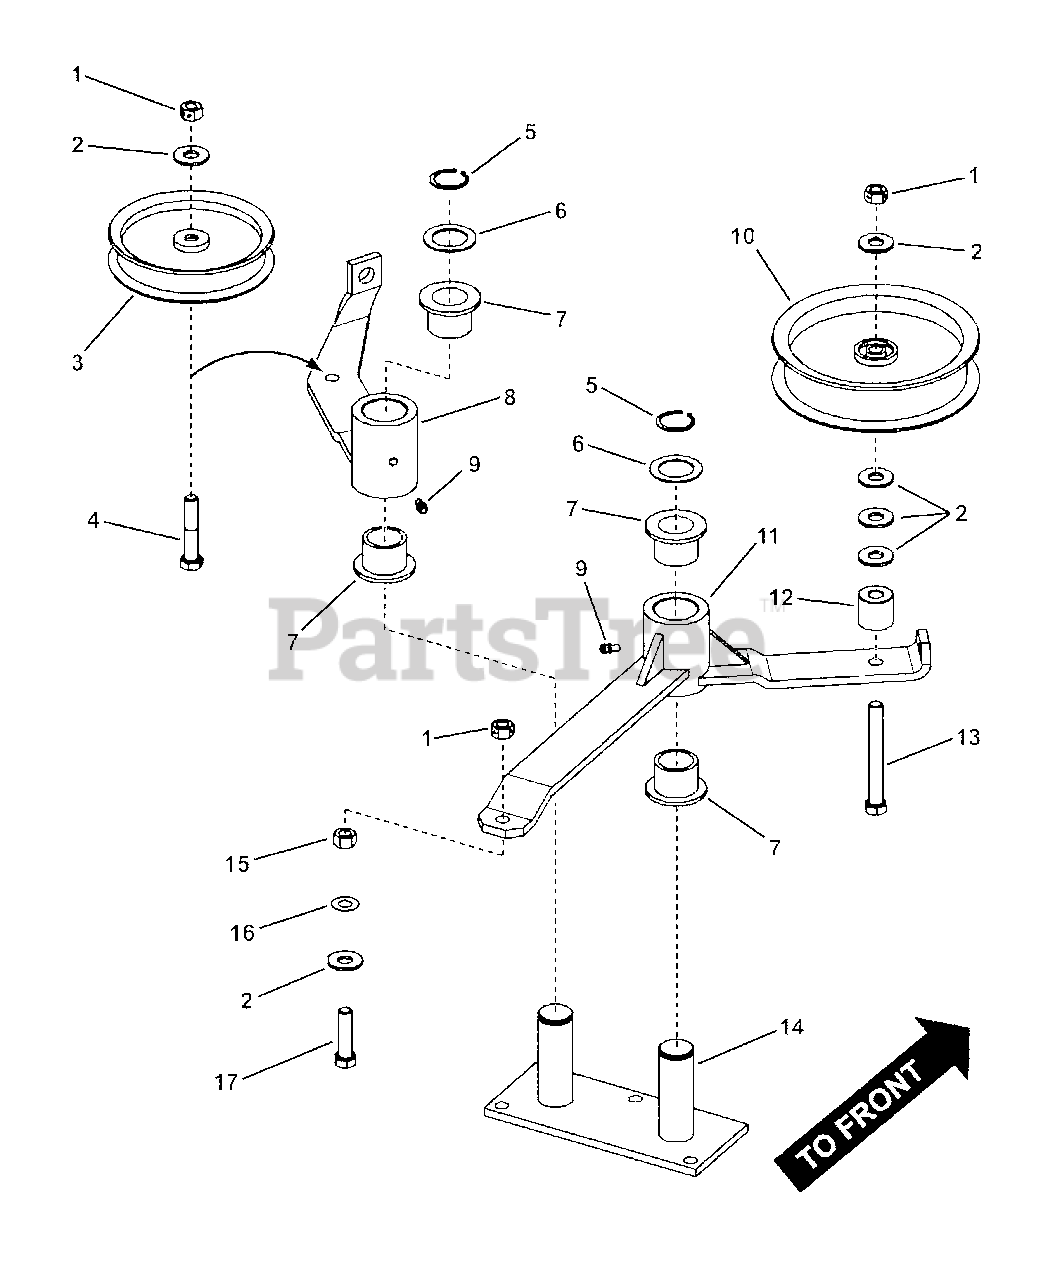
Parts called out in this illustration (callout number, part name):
1	NUT, 3/8-16 Hex Center Lock, GR 5 or B
2	WASHER, 3/8" USS
3	PULLEY, Idler
4	BOLT, 3/8-16 X 2, GD5, CZ
5	RING, 1" External Retaining
6	BUSHING, Machine
7	BUSHING, Flange
8	WELDMENT, Secondary Idler Arm
9	GREASE FITTING, 3/16 Straight (press-in)
10	PULLEY, Idler (5.00 O. D.)
11	WELDMENT, Primary Idler Arm, SPA521
12	SPACER, Idler Pulley
13	BOLT, 3/8-16 x 3-1/4" Hex Head, GR 5
14	WELDMENT, Idler Pivot
15	NUT, 3/8-16 Hex, GR 5
16	RETAINER, 3/8" Bolt
17	SCREW, 3/8-16 x 1-1/2" Hex Head Cap, GR5
